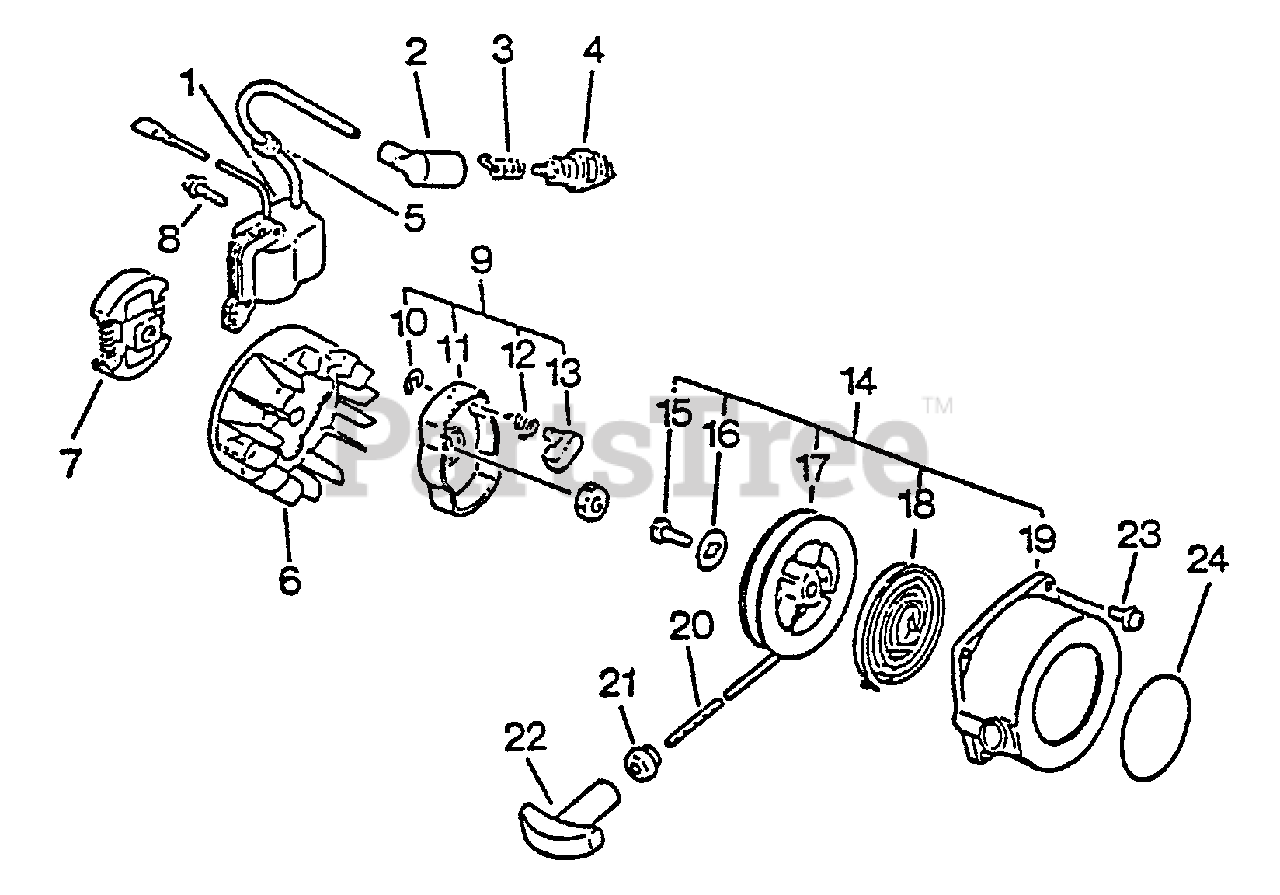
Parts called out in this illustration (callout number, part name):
1	COIL, IGNITION
2	CAP, SPARK PLUG
3	TERMINAL, SPARK PLUG
4	SPARK PLUG - BPM7A
4	SPARK PLUG - CJ-7Y
4	SPARK PLUG - BPMR7A
4	SPARK PLUG - RCJ7Y
6	FLYWHEEL
7	CLUTCH ASSY
8	SCREW 4×22
9	STARTER PAWL ASSY
10	E-RING 4
11	CATCHER, PAWL
12	SPRING, RETURN
13	PAWL, STARTER
14	STARTER ASSY
16	WASHER
17	REEL, ROPE
18	SPRING, RECOIL
19	CASE, RECOIL STARTER
20	ROPE, STARTER
21	GUIDE, ROPE
22	GRIP, STARTER
23	SCREW 4×16
24	LABEL, ECHO
